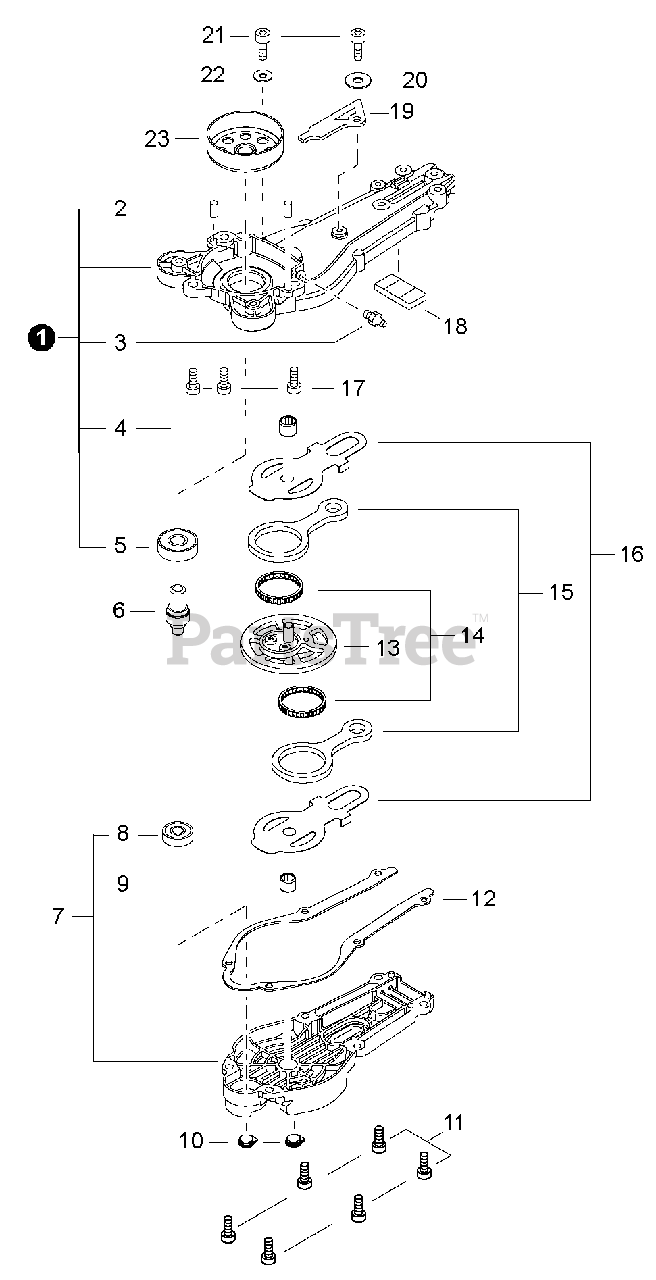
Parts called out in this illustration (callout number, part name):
1	GEAR CASE ASSY
2	PIN - LOCATING
3	FITTING, GREASE
4	BEARING, NEEDLE - 8
5	BEARING, BALL - 6001 DDU
6	SHAFT, PINION
7	GEAR CASE COVER ASSY
8	BEARING, BALL - 608ZZ
9	BEARING, NEEDLE - 8
11	SCREW - 5X16
12	GASKET, GEAR CASE
13	GEAR - SPUR
14	BEARING, NEEDLE - 30
15	ROD, CONNECTING
16	PLATE, GEAR CASE
17	SCREW - 6X20
18	SEAL, FELT
19	CUSHION
20	WASHER - 5
21	SCREW - 5
22	WASHER - 5
23	DRUM, CLUTCH
